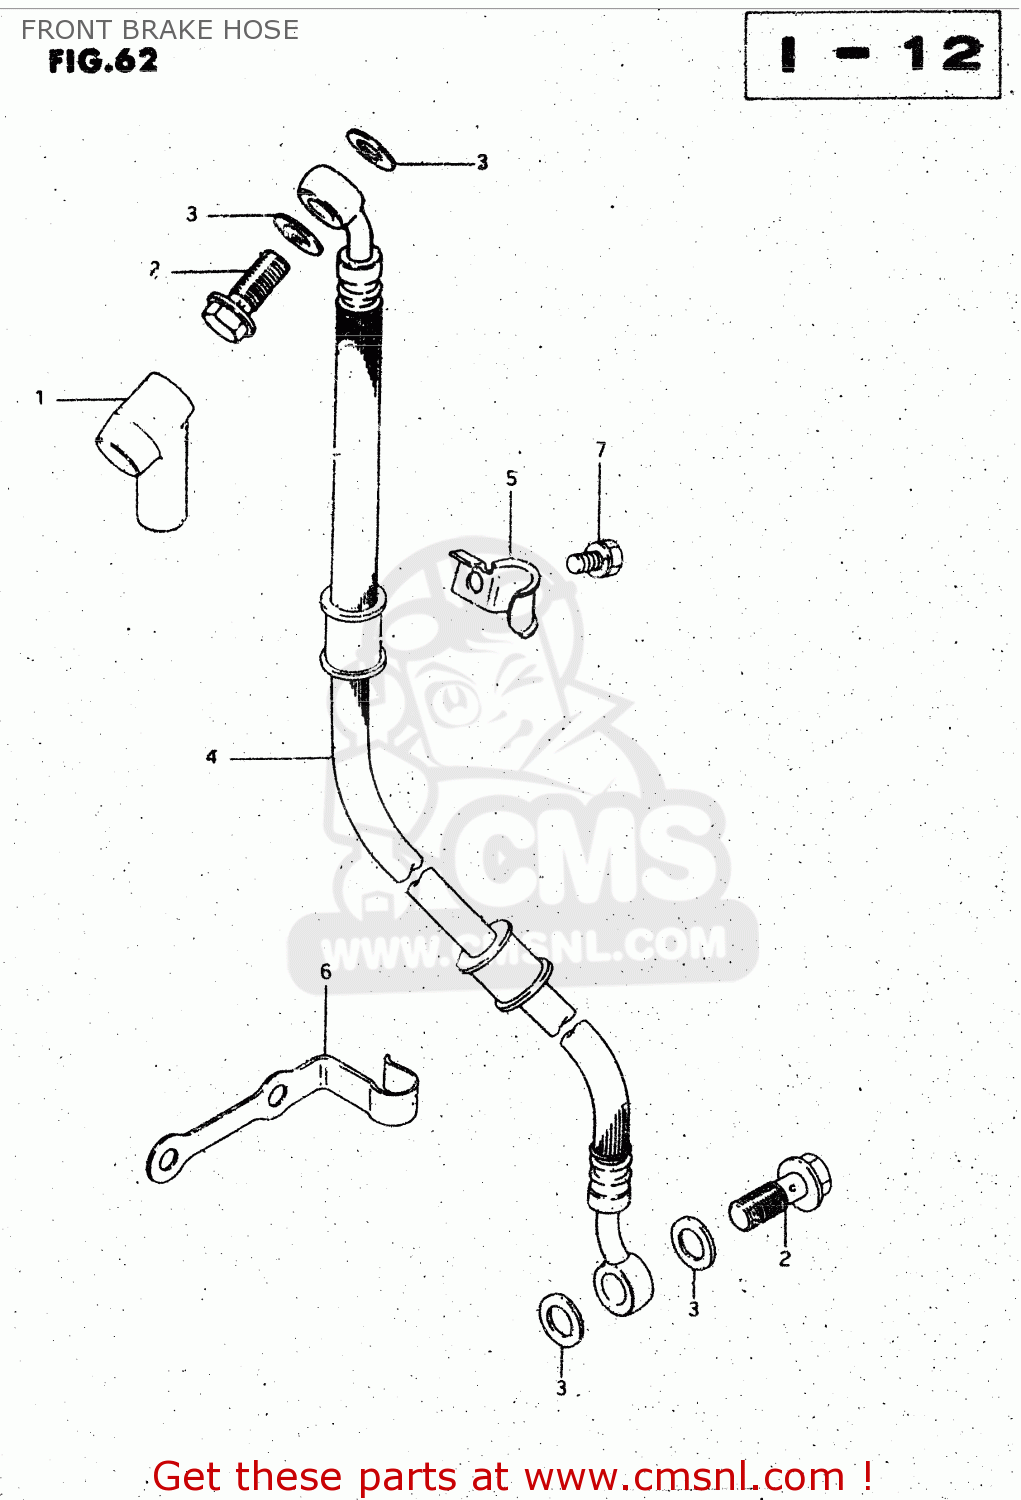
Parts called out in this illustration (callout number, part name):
1	BOOT,MASTER CYLINDER
2	BOLT UNION
3	WASHER(10X15X1.5)
4	HOSE, BRAKE
5	CLAMP,BRAKE HOSE
6	CLAMP,BRAKE HOSE
7	BOLT
